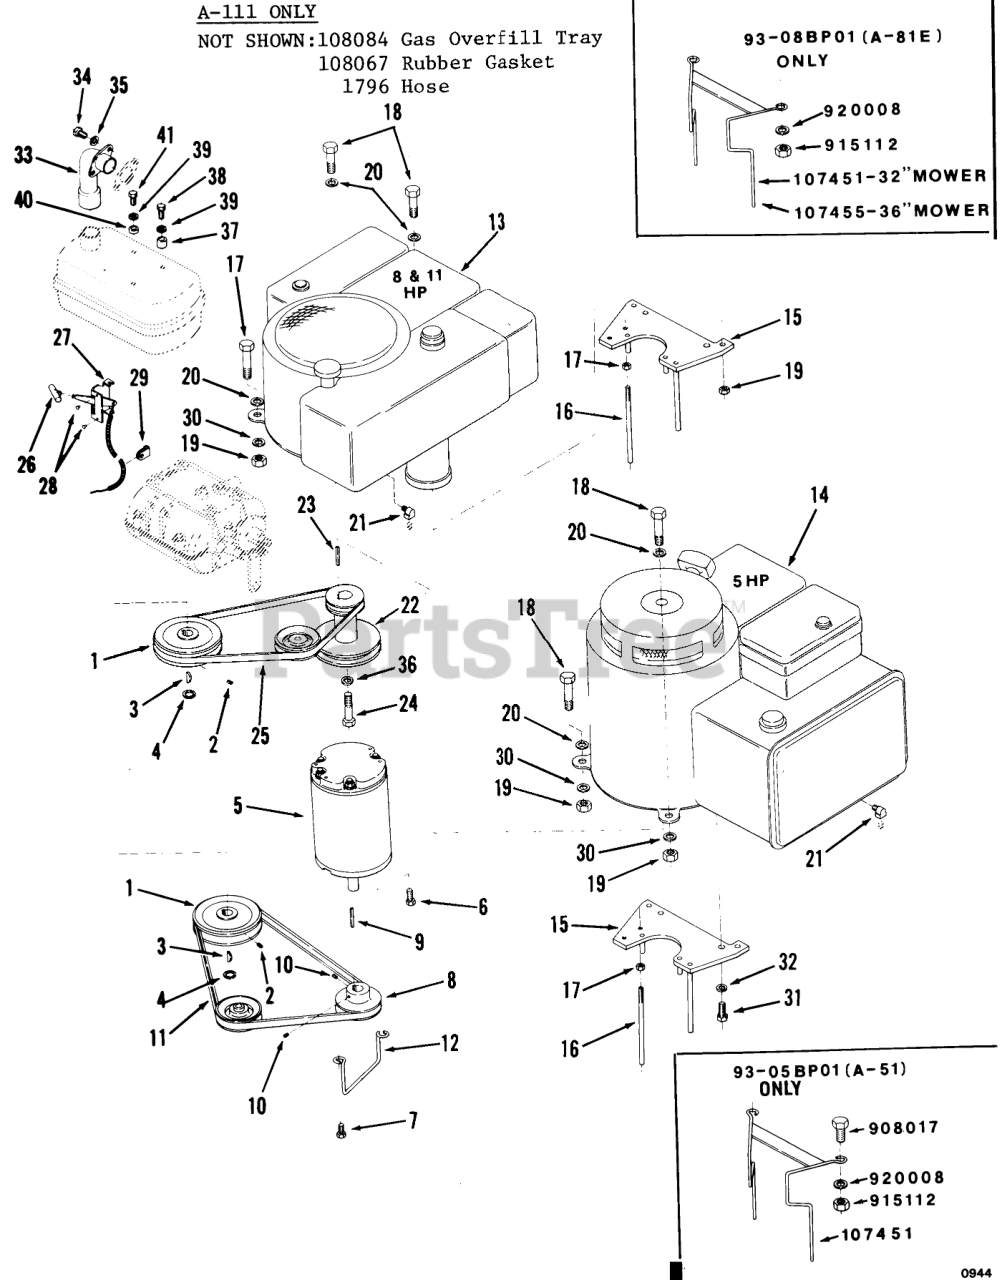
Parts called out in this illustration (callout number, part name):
1	PULLEY
1	Pulley-Trans
2	Set Screw
3	Key
4	SNAP RING- 5/8 EXT
5	Motor-Traction
6	Bolt
7	Bolt
8	Pulley-Traction Motor
9	KEY-STRAIGHT
10	Set Screw
11	Drive Belt
12	Belt Guide-Traction Motor
13	Engine 8 H.P.-B & S Model 191707 Type 5639-01 A-81E Only
13	Engine 11 H.P.-B & S Model 252707 Type 0188-01 A-111 Only
13	Engine 8 H.P.-B & S Model 191702 Type 5648-01 A-81R Only
14	Engine 5 H.P.-B & S Model 130902 Type 0584-01
15	Belt Guide-Engine
16	Rod-Belt Guide
17	Jam Nut 5/16-18
18	Bolt
19	Nut
